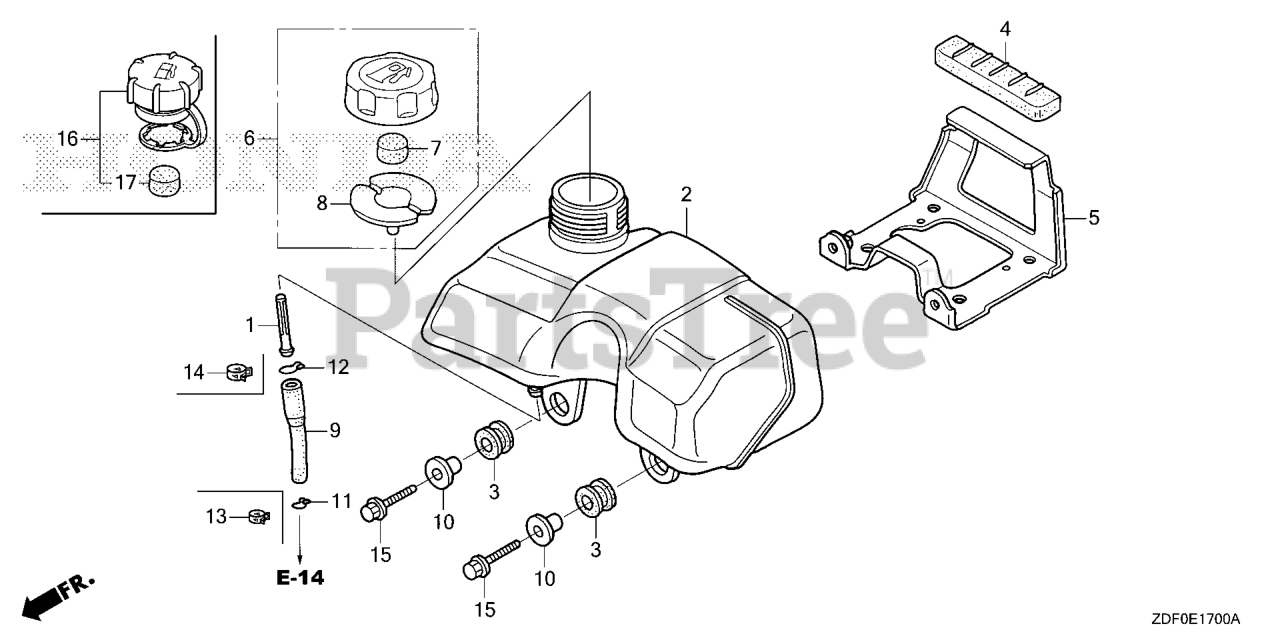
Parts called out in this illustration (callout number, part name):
1	FILTER, FUEL
2	TANK, FUEL
3	RUBBER A, TANK MOUNTING
4	RUBBER B, TANK MOUNTING
5	STAY, FUEL TANK
6	CAP ASSY., FUEL TANK
7	SPONGE, FUEL CAP BREATHER
8	GASKET, FUEL CAP
9	TUBE A, FUEL
10	COLLAR, CANISTER MOUNTING
13	CLIP, TUBE (D8)
14	CLIP, TUBE (10.5MM)
15	BOLT, FLANGE (6X20)
